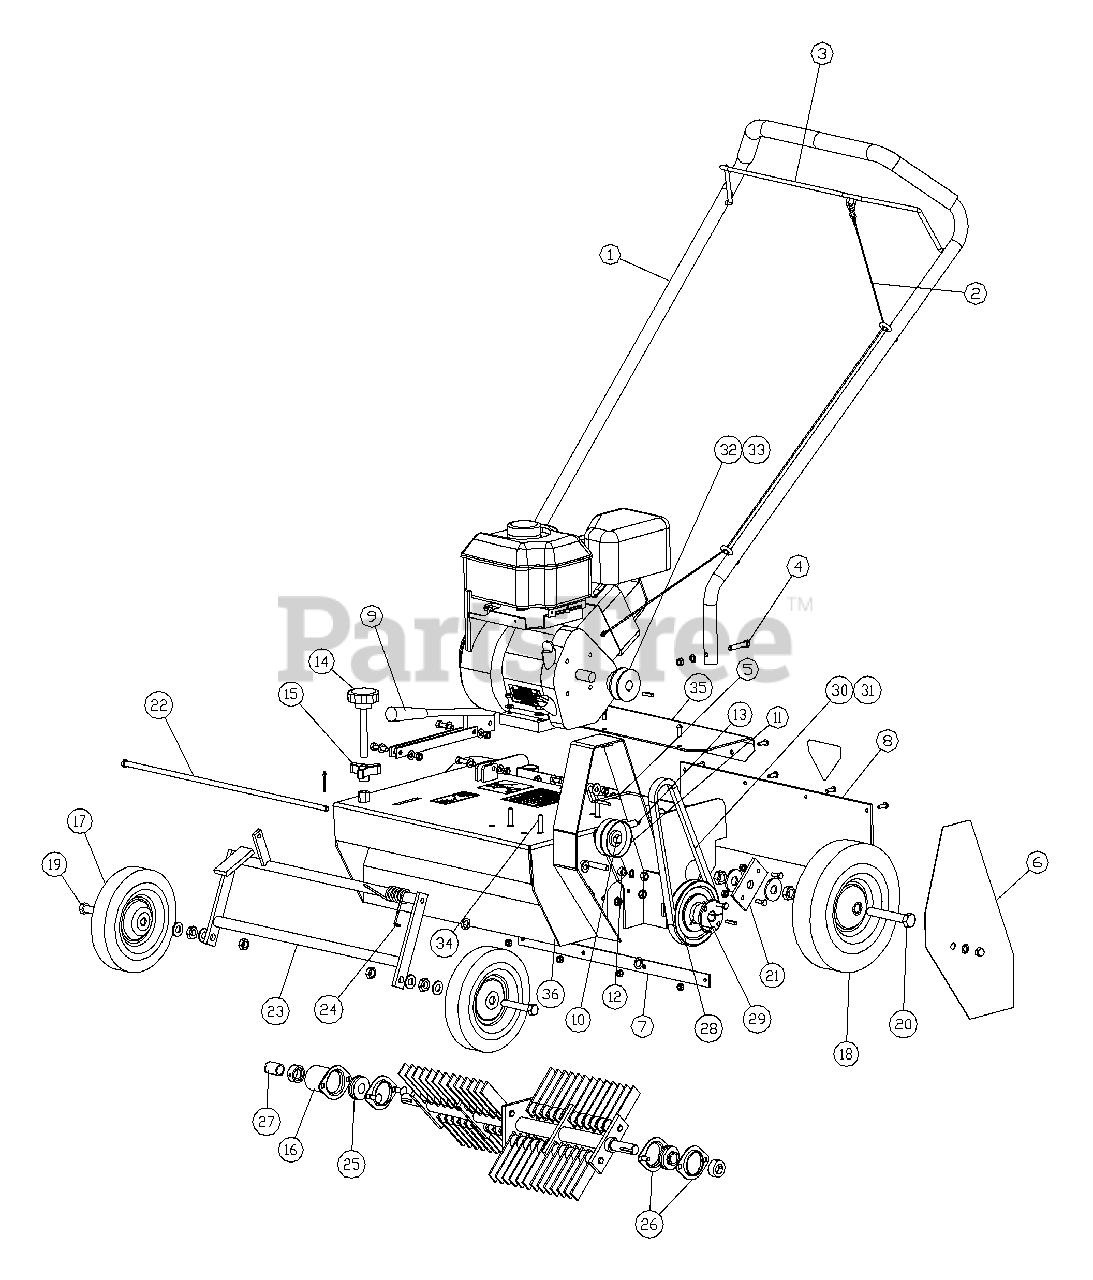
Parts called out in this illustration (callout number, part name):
1	Handle Assembly.
2	Clutch Cable Assembly.
4	Bolt kit, handle
5	Belt keeper kit
6	Belt Guard Kit
7	Deflector Kit
8	Deflector, neoprene
9	Depth Lever Assembly.
10	Idler Assembly Kit
11	Pulley, idler 2 3/4 OD
12	Mounting Arm, idler pulley
13	Spring, idler return
14	Depth Adjustments Knob
15	3 - pronged lock depth knob
16	Rotor guard
17	Front Wheel, 8 x 1 3/4, ball bearing
18	Rear Wheel, 10 x 2 3/4, ball bearing
19	Bolt kit for front wheel
20	Bolt kit for rear wheel
21	Wheel plate kit
22	Lift Arm Rod Kit
23	Lift Arm Assembly Kit
24	Torsion spring
25	Bearing, 3/4 with locking collar
26	Stamping Kit
27	Rotor cap, 3/4 ID
28	V - Pulley, B-5.0 OD, tapered bore
29	Bushing kit
30	V - Belt, B-34, special
31	V-Belt, B36, special
32	V - Pulley engine kit for 3/4 bore
33	V - Pulley engine kit for 1" bore
34	Engine Bolt Kit
35	Deck Cover Kit - DT18
36	Deck, DT18
